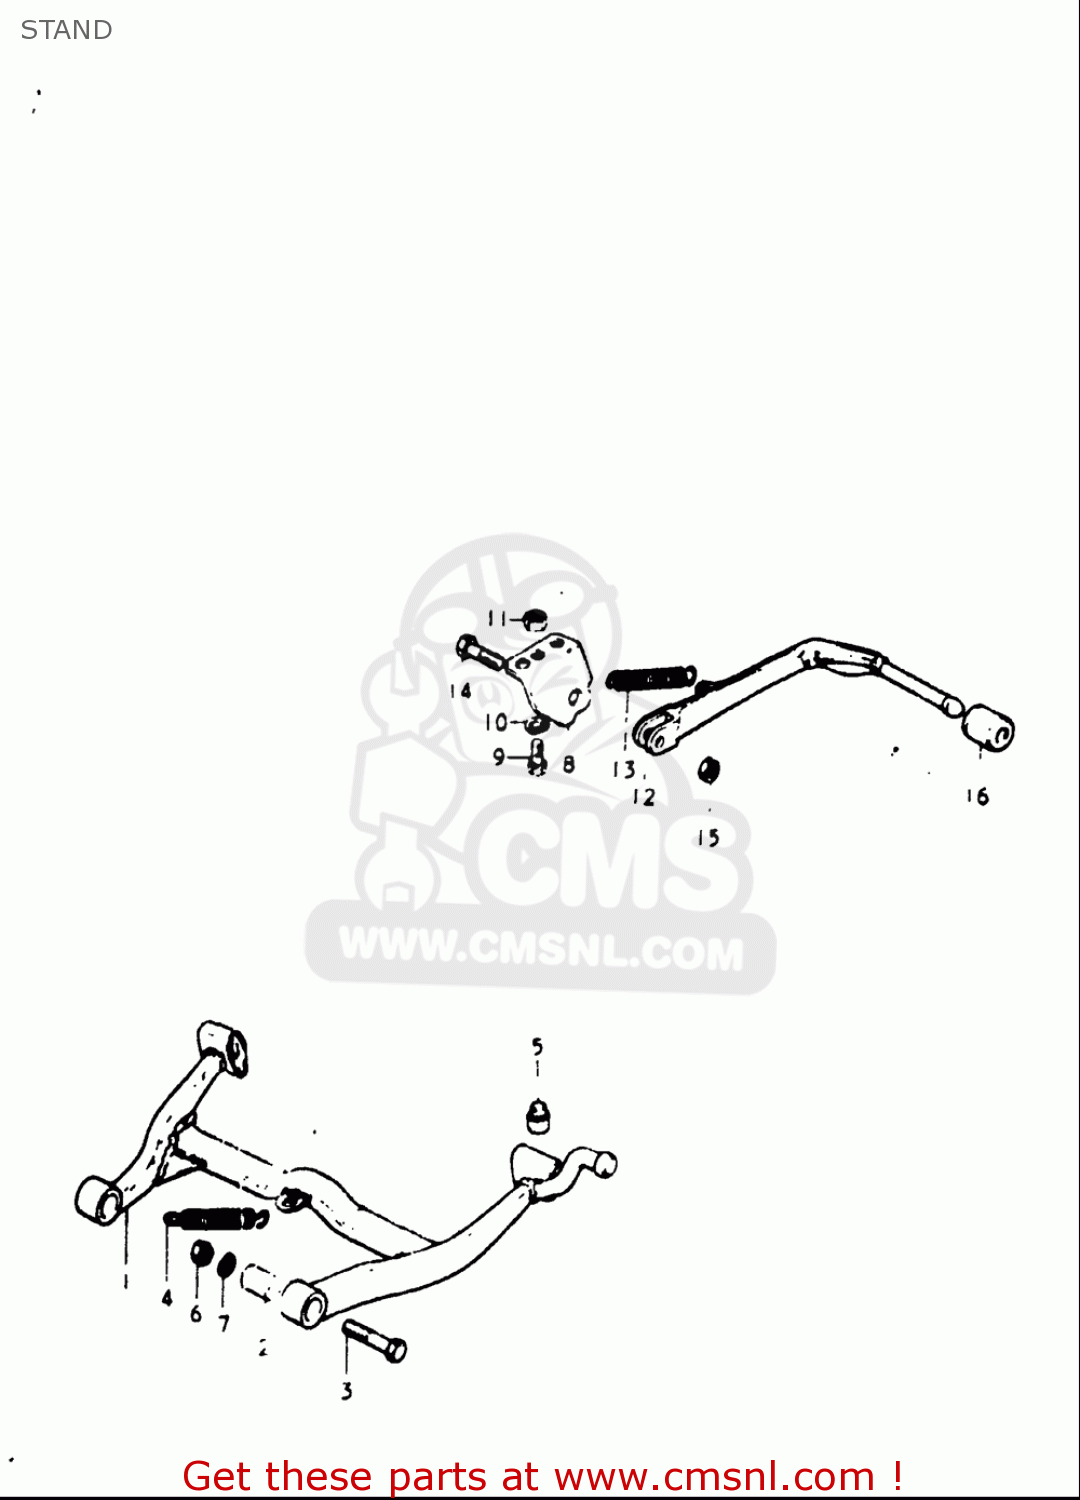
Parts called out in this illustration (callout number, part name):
2	SPACER(10.5X16X30)
3	BOLT(10X48)
4	SPRING
5	CUSHION
6	NUT
7	WASHER,LOCK
9	BOLT(10X27)
10	WASHER,LOCK
11	NUT
13	SPRING
14	BOLT(10X27)
15	NUT
16	CUSHION
